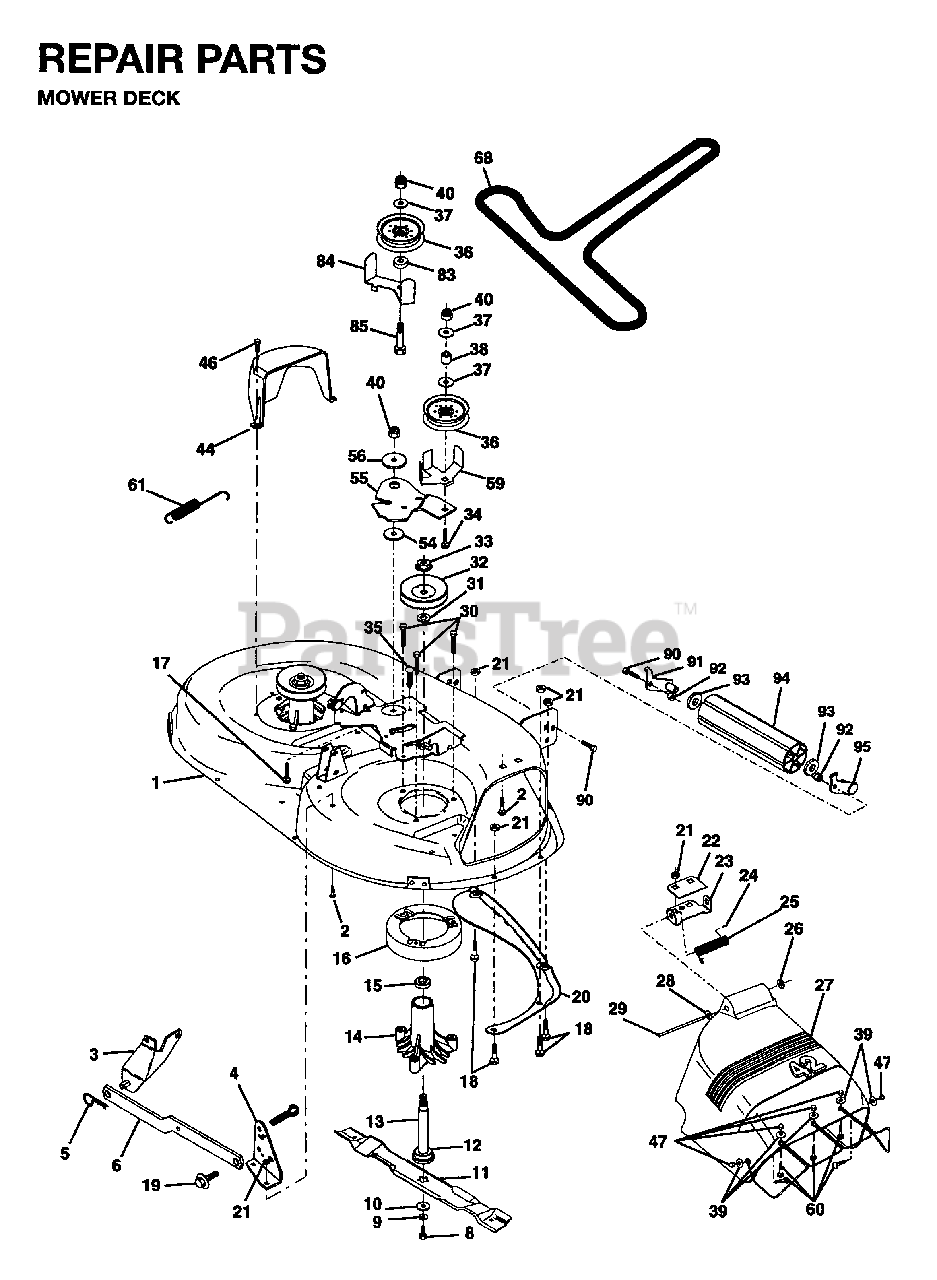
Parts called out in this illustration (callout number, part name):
1	DECK 42"
2	BOLT
3	BRKT ASM SWAY BAR
4	BRKT DECK SW BAR
5	RETAINER SPRING
6	REAR SUSP ARM
8	BLADE BOLT
9	WASHER, LOCK 3/8
10	WASHER.BLADE
11	BLADE 42"
12	BEARING
13	SHAFT ASM VENT
14	HSG MANDREL
16	STRIPPER
17	BOLT CARRIAGE
18	BOLT
19	BOLT SHD 5/16-18
20	BAFFLE
21	LOCKNUT
22	STIFFENER BRACKET
23	DEFLECTOR BRACKET
24	CAP-SLEEVE LT
25	SPRING TORSION
26	NUT PUSH M
28	WASHER - 15X7.3X1.6
29	ROD.HINGE
30	SCREW
31	WASHER
32	MANDREL PULLEY
33	NUT
35	FASTENER.XMAS.TREE
36	FLAT IDLER PULLEY
37	WASHER
38	IDLER SPRING SPACER
40	LOCKNUT
44	GUARD MANDREL LH BLACK
46	SCREW.1/4-20X5/8
54	HARDENED WASHER
55	IDLER ARM
56	SPACER RETAINER
59	GUARD, BELT
61	SPRING EXTENSION
68	V-BELT TRIPATH
84	KEEPER BELT
85	BOLT
91	BRACKET LH (A)
92	LOCKNUT
94	NOSE ROLLER
95	BRACKET RH (B)
